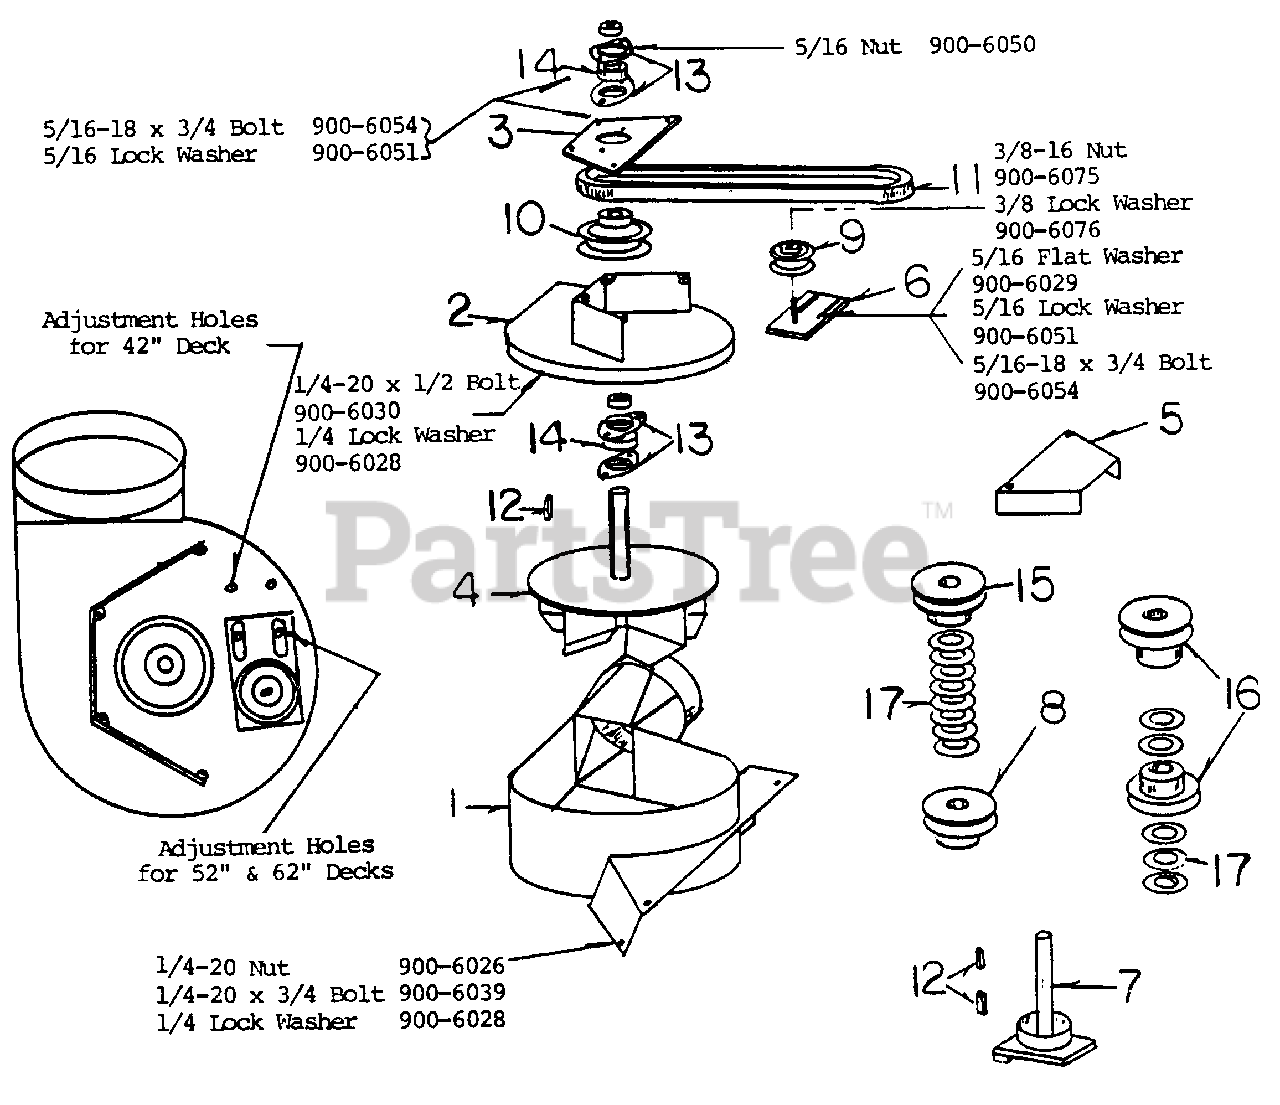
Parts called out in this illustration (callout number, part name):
1	Blower Housing 42" 52" Deck
3	Blower Bearing Plate
4	Blower Blade Assembly
6	Belt Tightener
7	Long Spindle Shaft 42"52" Deck
8	Pulle 42 Dock
9	Idler Pulley
10	Blower Pulley
11	Bolt 42" Deck /16 or 18 HP
12	Key
13	Flange
14	3/4" Bearing / lock collar
15	Spindle Pulloy 42" Dock / 16 or 18 HP
16	Spindle Pulloy 5Z" Deck
